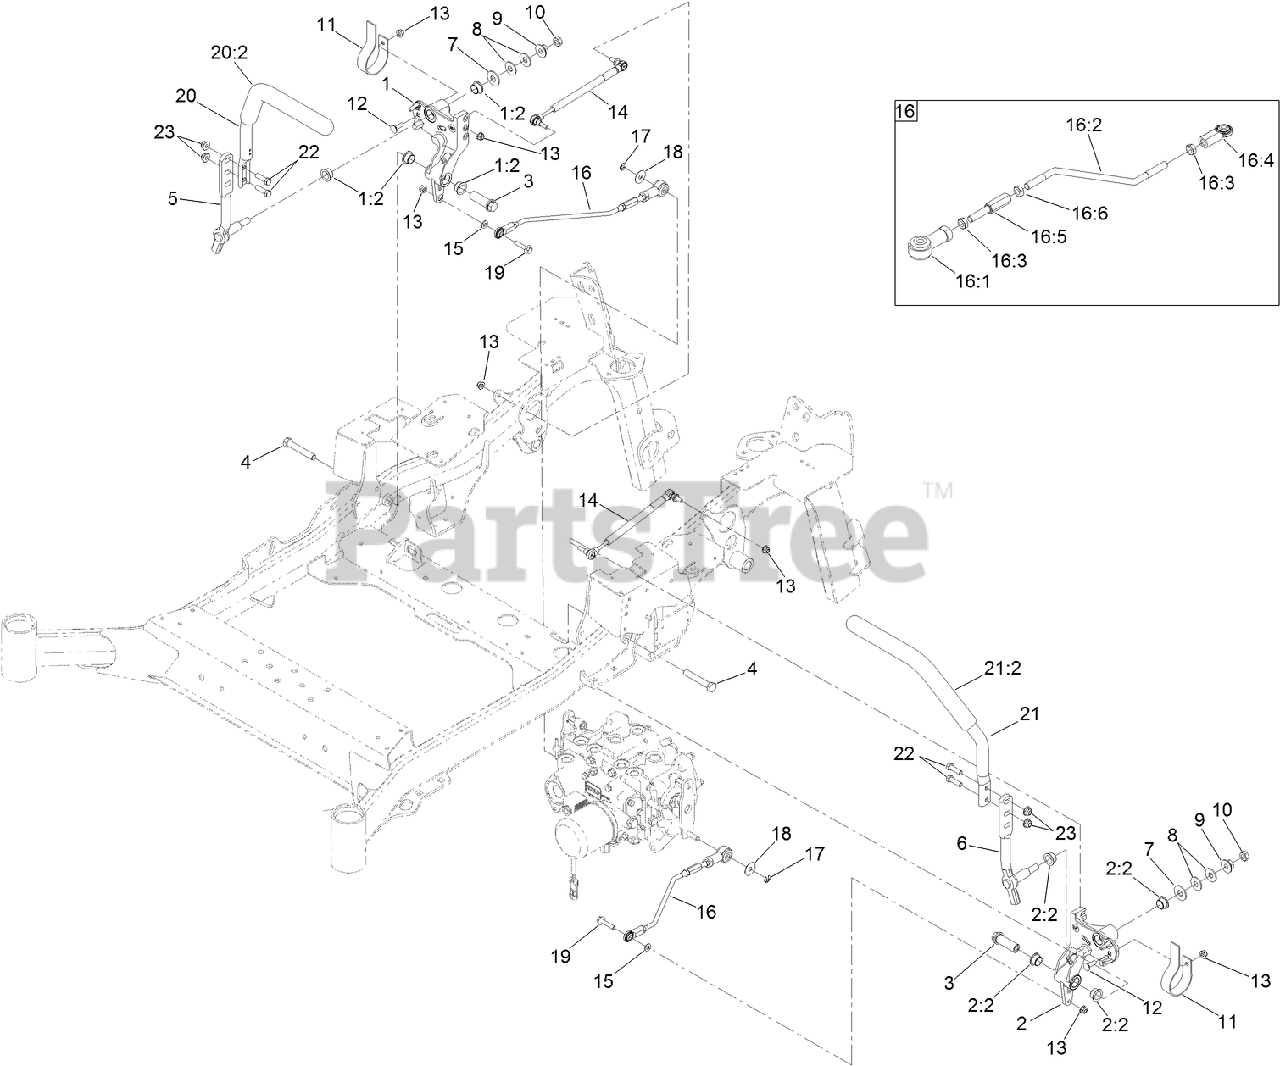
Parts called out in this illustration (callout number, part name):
1	RH MOTION CONTROL AND BUSHING ASM
1:2	BUSHING-FLANGE
2	LH MOTION CONTROL AND BUSHING ASM
2:2	BUSHING-FLANGE
3	HUB-THREADED
4	SCREW-HH
5	LEVER-CONTROL MOTION, RH
6	LEVER-CONTROL MOTION, LH
7	WASHER-FLAT
8	WASHER-SPRING
9	NUT-HF
10	NUT-JAM
11	SPRING-LEAF
12	BOLT-CARR
13	NUT-HF, NI
14	DAMPER-CONTROL, MOTION
15	WASHER-PLAIN
16	FRONT LINKAGE ROD ASM
16:1	END-ROD, ISOLATED
16:2	ROD-LINKAGE, REAR
16:3	NUT-HJ
16:4	JOINT-BALL, END
16:5	ROD-ADJUSTMENT
16:6	NUT-HEX JAM, LH
17	RING-RETAINING
18	WASHER-PLAIN
19	SCREW-HHF
20	RH STEERING HANDLE ASM
20:2	GRIP-CONTROL, LEVER
21	LH STEERING HANDLE ASM
21:2	GRIP-CONTROL, LEVER
22	SCREW-HH
23	NUT-HF, NI
